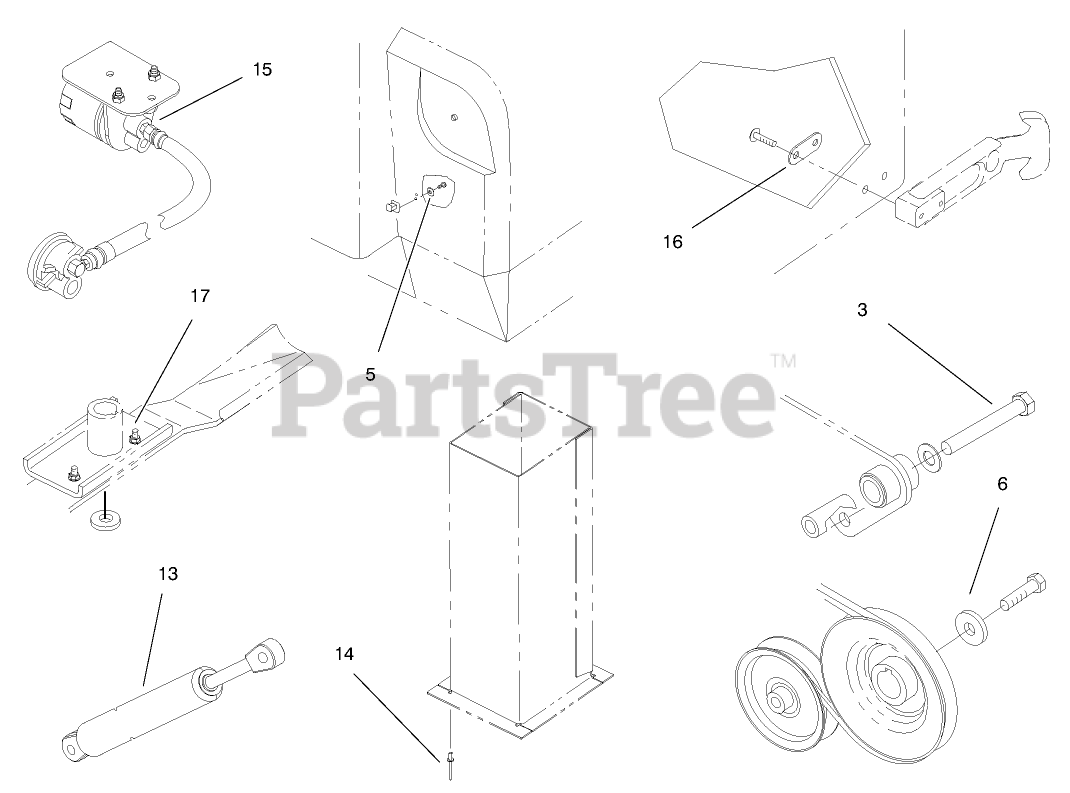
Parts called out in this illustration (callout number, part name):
3	SCREW-HH
5	WASHER-FLAT
6	WASHER
13	Damper-Control
14	RIVET
15	KIT - FILTER, REMOTE OIL
16	PLATE - BACKER
17	KIT - SHEAR BOLT
